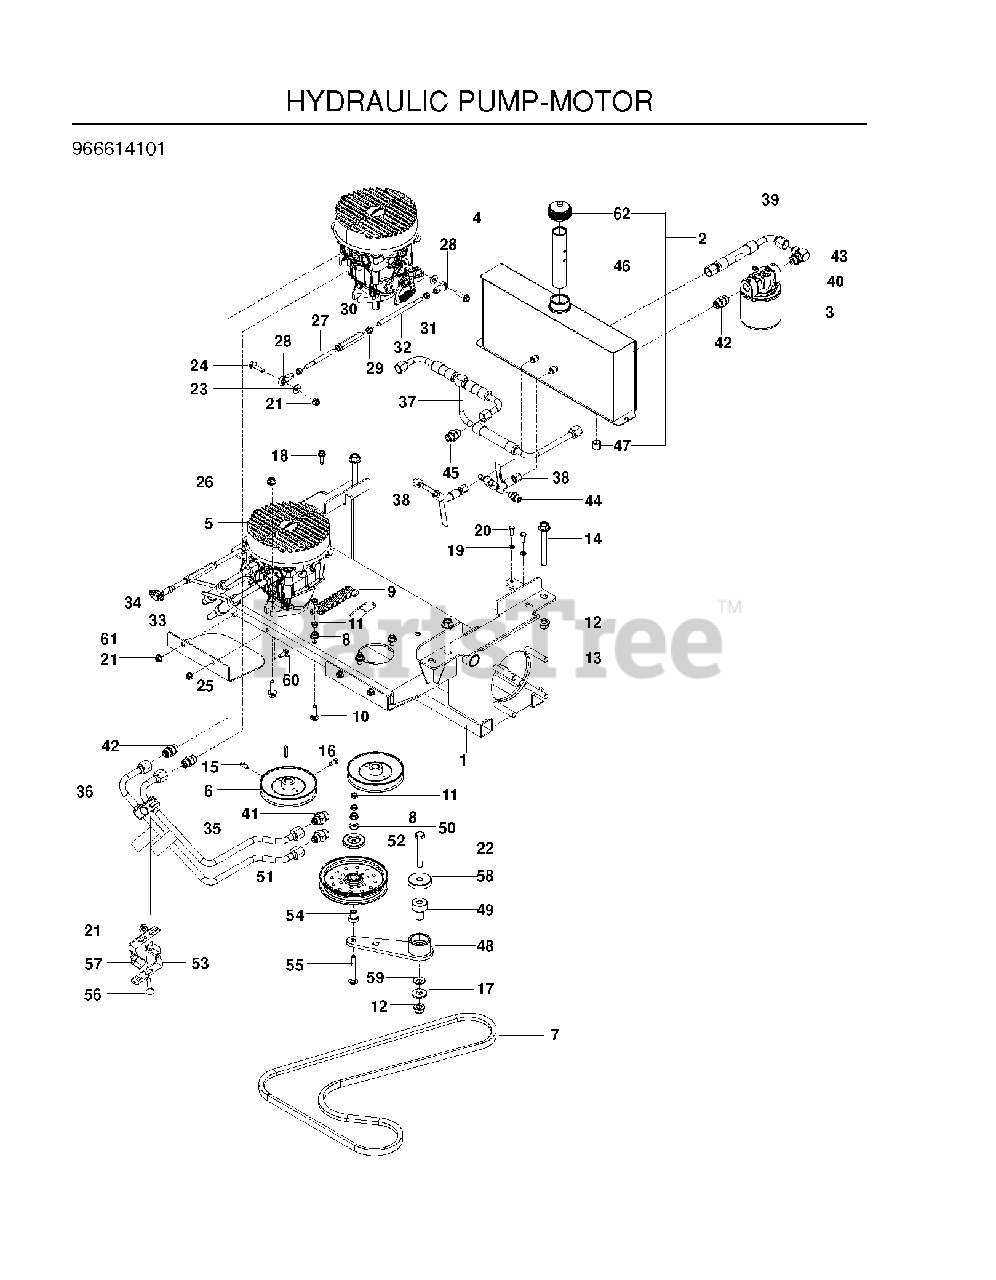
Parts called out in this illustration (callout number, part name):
1	FRAME, NYDR SUB, BLK
2	ASSEMBLY, RESERVOIR, OIL
3	FILTER 25 MICRON
4	HG_PUMP, 12CC RT
5	HG_PUMP, 12CC LT
6	PULLEY, PUMP 15MM
7	BELT, "B", 75.5"
8	NUT 3/8C WHIZ
9	SPRING, PUMP
10	RHSNB 3/8-16 X 1-1/4
11	NUT HEX 3/8-16 NYLON, THIN
12	NUT, 1/2-13 HEX FLG NYLOC ZD
13	HCS 1/2C X 2 3/4
14	HHFS 1/2-13 X 4.0 GD8 ZD
15	SCREW 5/16C X 5/8 SQ HEAD
16	KEY 5 MM SQ X 25 MM
17	WASH USS FLAT 1/2
18	RP BLT 5/16-18 X 1 THRD FORM D
19	LOCKWASHER 1/4"
20	HCS 1/4C X 5/8
21	5/16-18 NYLOC FLANGE NUT
22	HCS 1/2C X 3 1/4
23	WASHER 5/16 FLAT
24	HHFS 5/16-18 X 1.25 TPBLT GD 5
25	HHFS 3/8-16 X 1.25 GD 5
26	NUT 3/8-16 HEX FLG NYLOC ZD
27	LINKAGE, CONTROL, FT
28	BALL JOINT, RIGHT HANDED
29	NUT 3/8-24 JAM
30	TURNBUCKLE, 3/8
32	LINKAGE, CONTROL, RR
33	LINE, RT A
34	LINE, RT B
35	LINE, LT A
36	LINE, LT B
37	LINE, CHARGE
38	LINE, CASE
39	LINE, SUCTION
40	FILTER HEAD
41	CONNECTOR, STRAIGHT
42	FITTING, STRAIGHT F6400-8-8-0
43	ELBOW, 90 DEGREE
44	STRAIGHT FITG
45	FITTING, HYDRO
46	TUBE, ANTI-SPLASH
47	NUT 9/16-18 JIC CAP
48	ARM, IDLER, STEEL, W/BGS
49	PIVOT, BEARING
50	WASHER, 3/8 THICK
51	IDLER, FLAT, 5.5"
52	DUST SHIELD
53	BRACKET, CLAMP
54	PIVOT, IDLER
55	RHSNB 3/8-16 X 2.75
56	RHSNB 5/16-18 X 1-1/2 GR 5 ZD
57	RUBBER, VIBRATION, 1/2"
58	SHIELD, DUST
59	CONTACT BELLSPR 1/2
60	BOLT 5/16C X 3/4" CARRIAGE
61	SHIELD, PULLEY, BLK
62	CAP, HYDRAULIC
